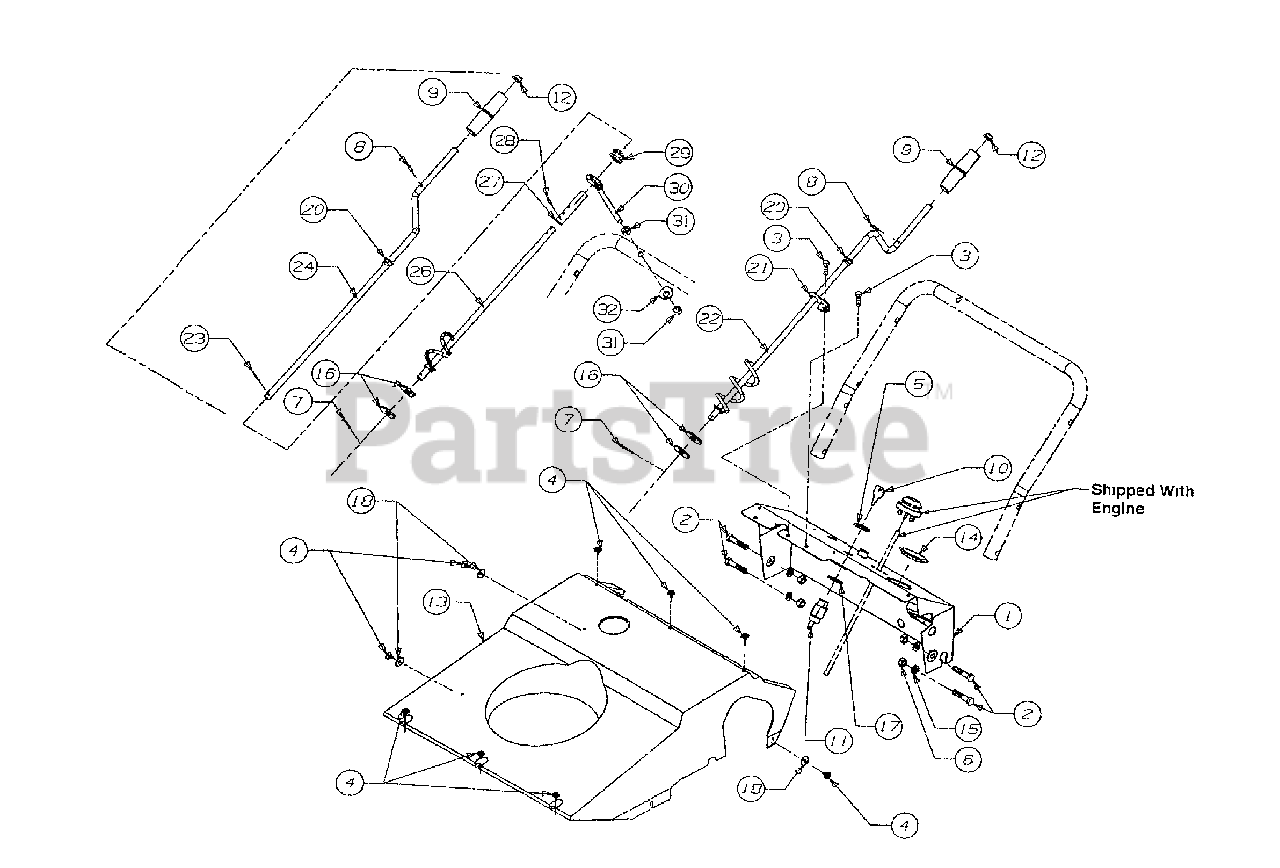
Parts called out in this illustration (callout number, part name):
3	Hex Tap Screw
4	Hex Tap Screw
7	Cotter Pin
9	Chute Crank Knob
10	Key-Ignition
11	Switch-Key
14	Plug
15	Lock Washer
16	Flat Washer
17	Internal Lock Washer
18	Flat Washer
20	Bushing
21	Bracket, Chute Crank
22	Crank Assembly, Chute
23	Cotter Pin
29	Grommet - Rubber
30	Eyebolt - Chute Crank
31	Nut - Hex
32	Washer - Saddle
